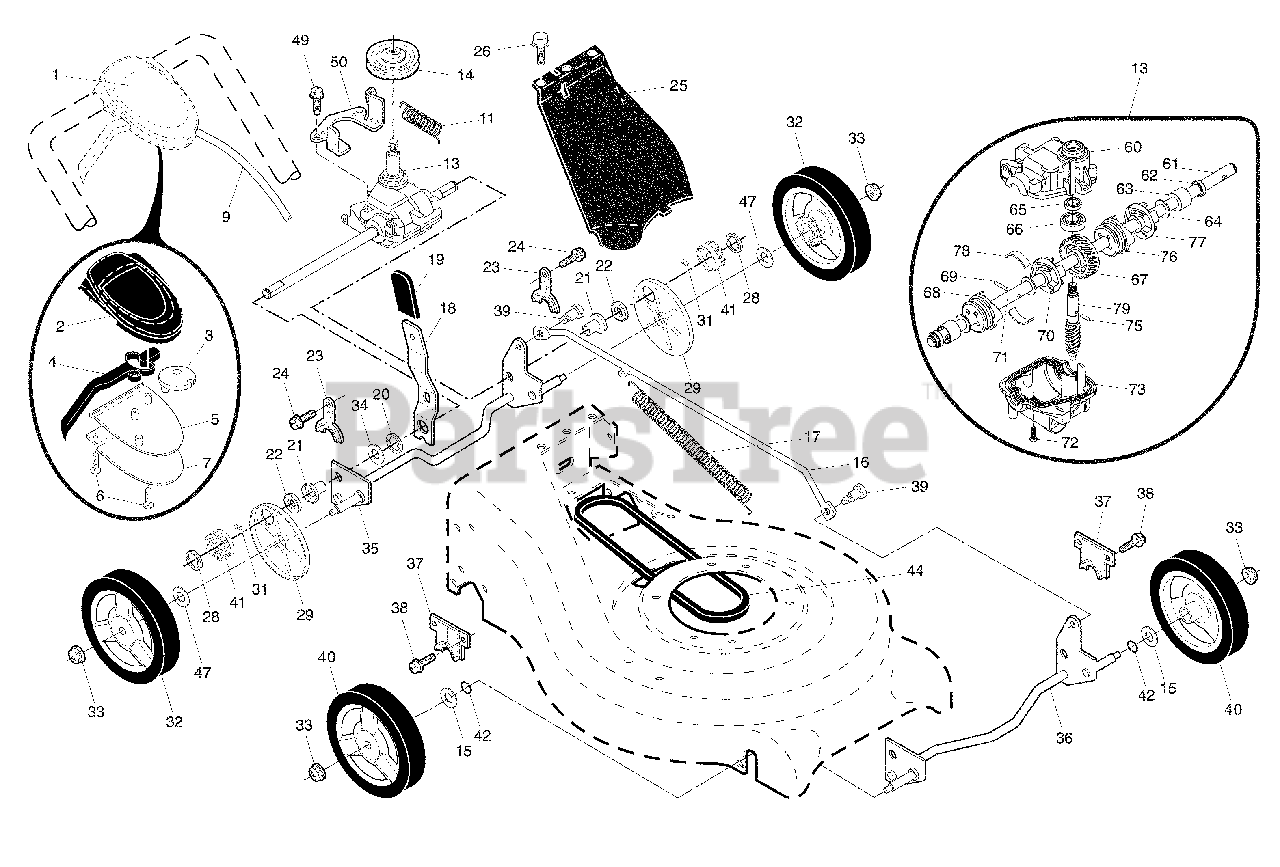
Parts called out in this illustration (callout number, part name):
1	Drive Control Assembly, Auto-Walk
2	Cover, Top, Auto-Walk Drive Control
3	Pulley
4	Lever, Auto-Walk Drive Control
5	Cover, Bottom, Auto-Walk Drive Control
6	Screw, Phillips Head #10 x 5/8
7	Plate, Trigger, Auto-Walk Drive Control
9	Cable, Drive Control
11	Spring, Return
13	Gear Case Assembly
14	Pulley, Drive
15	Washer, Flat
16	Rod, Connecting
17	Spring, Extension
18	Spring Selector
19	Knob, Selector Spring
21	Bearing, Support
22	Bearing, Ball
23	Retainer, Drive Assembly, Stamped
24	Screw, Tapping, Hex Head 1/4-20 x 3/4
25	Cover Drive
26	Screw, Threaded, Rolled #10-25 x 1/2
28	E-Ring 7/16
29	Cover, Dust, Wheel
31	Seal, Friction
32	Wheel & Tire Assembly, Rear
33	Nut, Hex, Flangelock 3/8-16
35	Shaft Assembly, Rear
36	Shaft Assembly, Front
37	Retainer, Front Shaft
38	Screw #12 x 5/8
39	Bolt, Shoulder, Semi-Gimlet Point
40	Wheel & Tire Assembly, Front 8 x 1-3/4
47	Washer 1/2 x 1-1/2 x .134
49	Screw, Hi-Lo Thread
50	Belt Keeper
60	Case, Upper
61	Shaft, Output, Long
62	Seal, Output Shaft
65	Seal, Worm Shaft
66	Bearing, Ball
67	Gear, 28 Teeth
68	Fixed Dog Clutch, LH
69	Pin, Output Shaft
70	Movable Dog Clutch, LH
71	Shaft, Output, Short
72	Screw, Case
73	Case, Lower
75	Pin, Worm Shaft
76	Movable Dog Clutch, RH
77	Fixed Dog Clutch, RH
78	Spring, Leaf
79	Shaft, Worm
